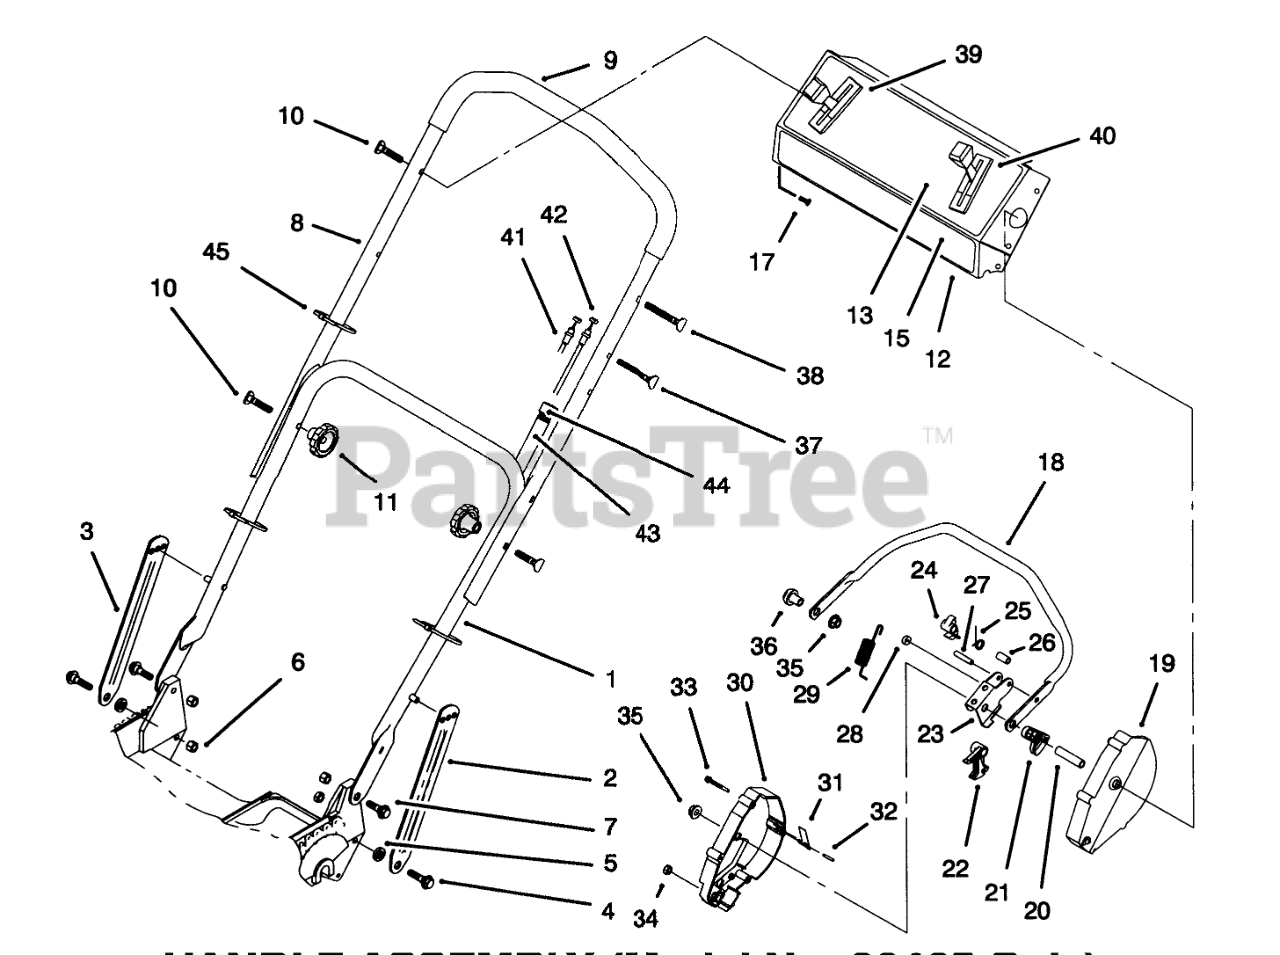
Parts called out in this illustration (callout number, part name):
1	ASM-Handle
2	Latch-Handle
3	Latch-Handle
4	SCREW-SHOULDER
5	SPACER
6	NUT-LOCK, NI
7	SCREW-SHOULDER
8	Handle-Upper
9	Grip-Foam
10	SCREW-HANDLE
12	Panel-Control (Incl. Ref. #13)
13	DECAL - INSRTUCTION
15	DECAL - CONSOLE
17	SCREW-TAP
18	Bar-Control
19	HOUSING-CONTROL, LH
20	TUBING-SPACER
21	LEVER-TRACTION
22	ROCKER
23	LEVER-CABLE
24	HOOK-CONTROL
25	SPRING-TORSION
26	SPACER
27	PIN-ROLL, SLOTTED
28	WASHER-NYLON
29	SPRING-DETENT
30	Housing-Control
31	SPRING-LEAF
32	PIN-INSERT
33	SCREW-HWHTF
34	NUT-LOCK NI
35	NUT-LOCK NI
36	SPACER-SUPPORT
37	SCREW-HANDLE
38	OBS MATERIAL EXCEPT FOR SERVICE
39	CONTROL-SPEED, GROUND
40	THROTTLE CONTROL
41	CLUTCH CABLE
42	TRACTION CABLE
43	CONTROL CABLE COVER
44	FITTING-RING
45	TIE-CABLE
